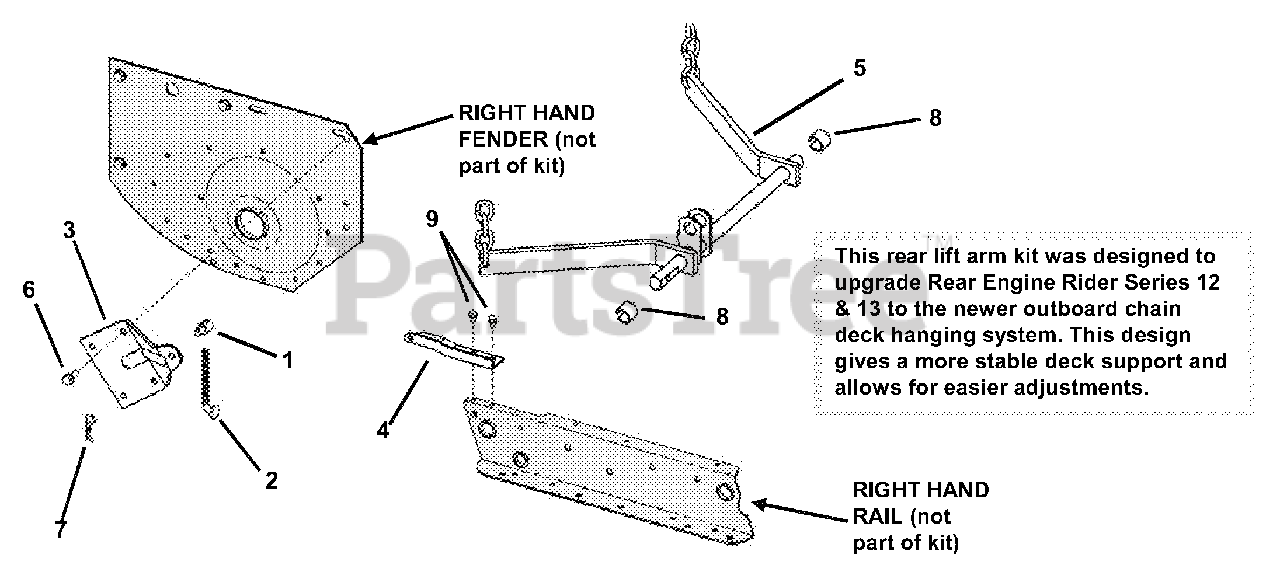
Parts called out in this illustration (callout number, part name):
1	SWIVEL, Adjustable
2	HOOK, Chain (Adjuster)
3	WING, Rear
4	BRACKET, Deck Lift
5	WELDMENT, Rear Lift Arm
6	SCREW, 5/16-18 x 3/4" Hex Washer Self-Tapping
7	HAIRPIN, 3/32 x 1-1/2"
8	RING, Rear Lift Arm- Blue
9	SCREW, 1/4-20 x 3/8" Self-Tap
